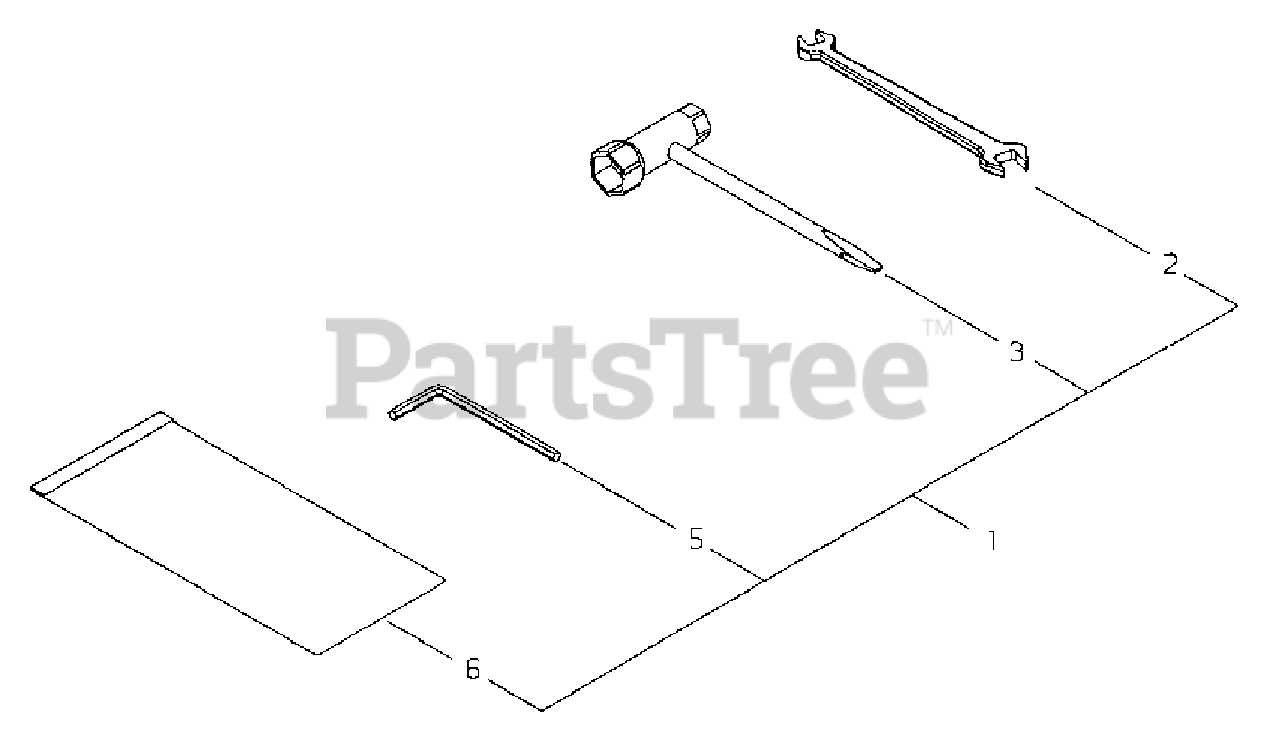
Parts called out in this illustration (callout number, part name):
1	TOOL KIT
2	SPANNER - 8X10mm
3	T-WRENCH - 13X16mm
5	HEX KEY - 4mm
6	BAG, TOOL
